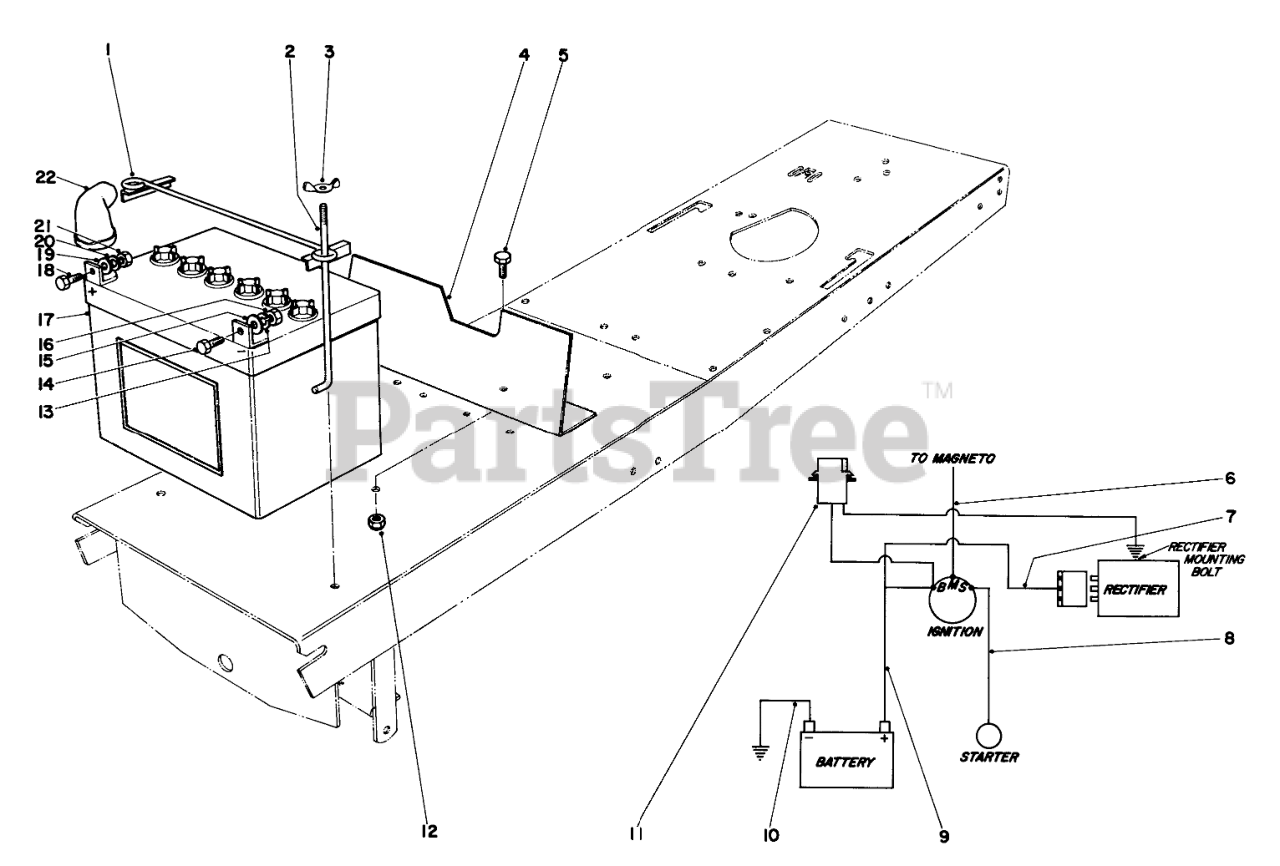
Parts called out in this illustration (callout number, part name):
1	Battery Clamp
2	BATTERY BOLT
3	NUT-WING
4	Heat Shield
5	SCREW-HH
6	Wire Assy. Switch To Magneto
7	Wire Assy. Switch to Rectifier
8	Wire Assy. Switch to Starter
9	Wire Assy. Switch to Battery
10	Wire Assembly
11	Wire Assy.
12	Nut
13	WASHER-LOCK
14	SCREW-HH
15	WASHER-FLAT
16	NUT-HEX
17	Battery
18	SCREW-HH
19	Washer
20	WASHER-LOCK
21	NUT-HEX
22	Battery Boot
